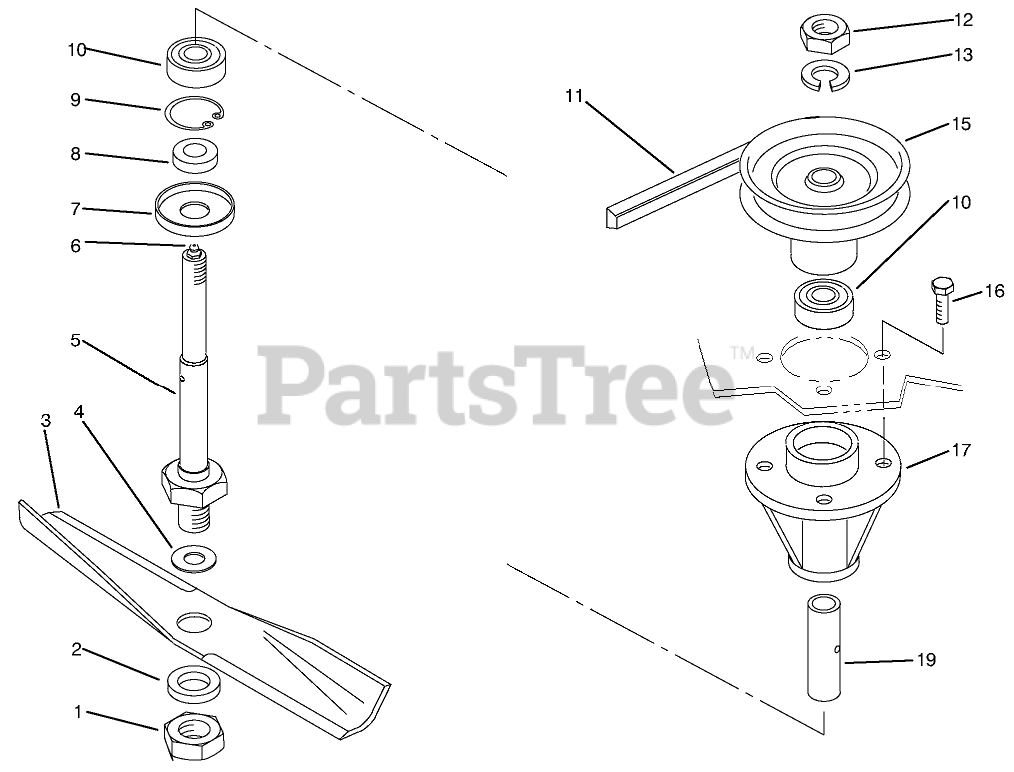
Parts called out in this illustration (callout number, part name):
1	NUT-JAM
2	WASHER-FLAT
3	14IN BLADE KIT
4	Washer
5	SHAFT-SPINDLE
6	FITTING-GREASE
7	CUP-SPINDLE
8	SPACER-BLADE
9	RING-RETAINING
10	BEARING-BALL
11	V-BELT
12	NUT-JAM
13	WASHER-LOCK
15	PULLEY
16	SCREW-HH
17	HOUSING-SPINDLE
